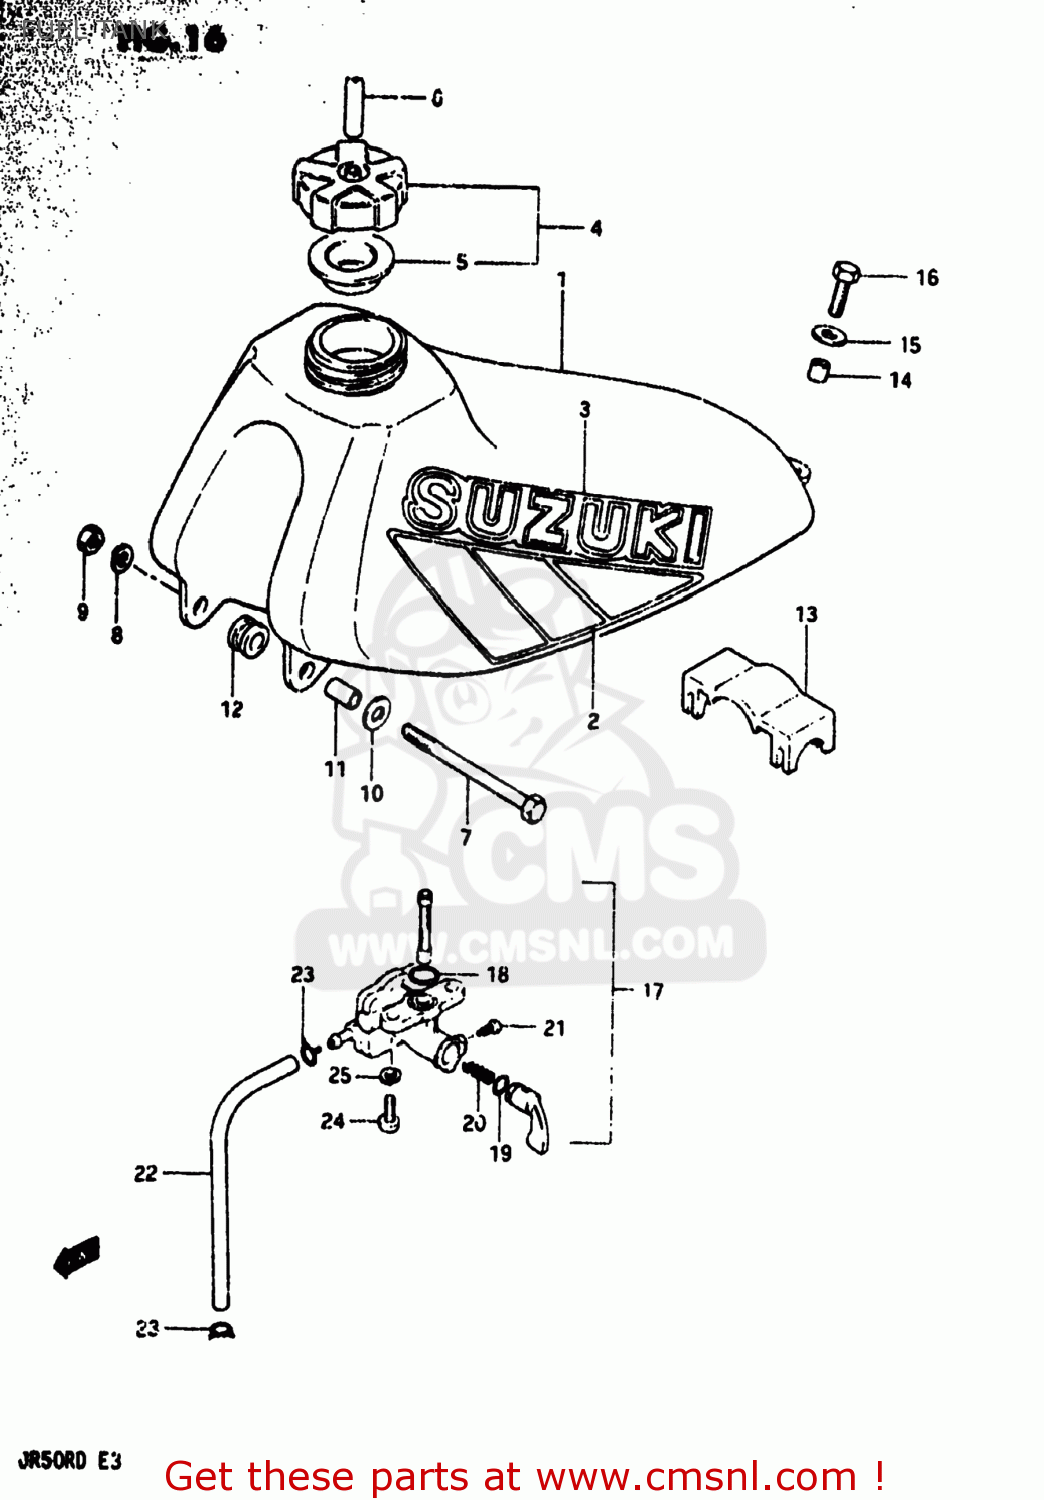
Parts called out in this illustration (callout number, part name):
1	TANK ASSEMBLY,FUEL
2	TAPE SET,FUEL TANK
3	EMBLEM,REAR FENDER
4	CAP,FUEL TANK FILLER
5	GASKET,FUEL TANK CAP (NAS)
6	HOSE
7	BOLT
8	LOCK WASHER
9	NUT
10	WASHER(6.5X18X1)
11	SPACER (6.8X10X11.5)
12	CUSHION
13	CUSHION,FUEL TANK UPR
14	SPACER (6.3X9.1X6.7)
15	WASHER(6.5X18X1)
16	BOLT, UPPER
17	COCK ASSY,FUEL
18	O RING
19	O RING,LEVER
20	SPRING,FUEL COCK VALUE
21	SCREW
22	HOSE
23	CLIP
24	SCREW
25	LOCK WASHER
